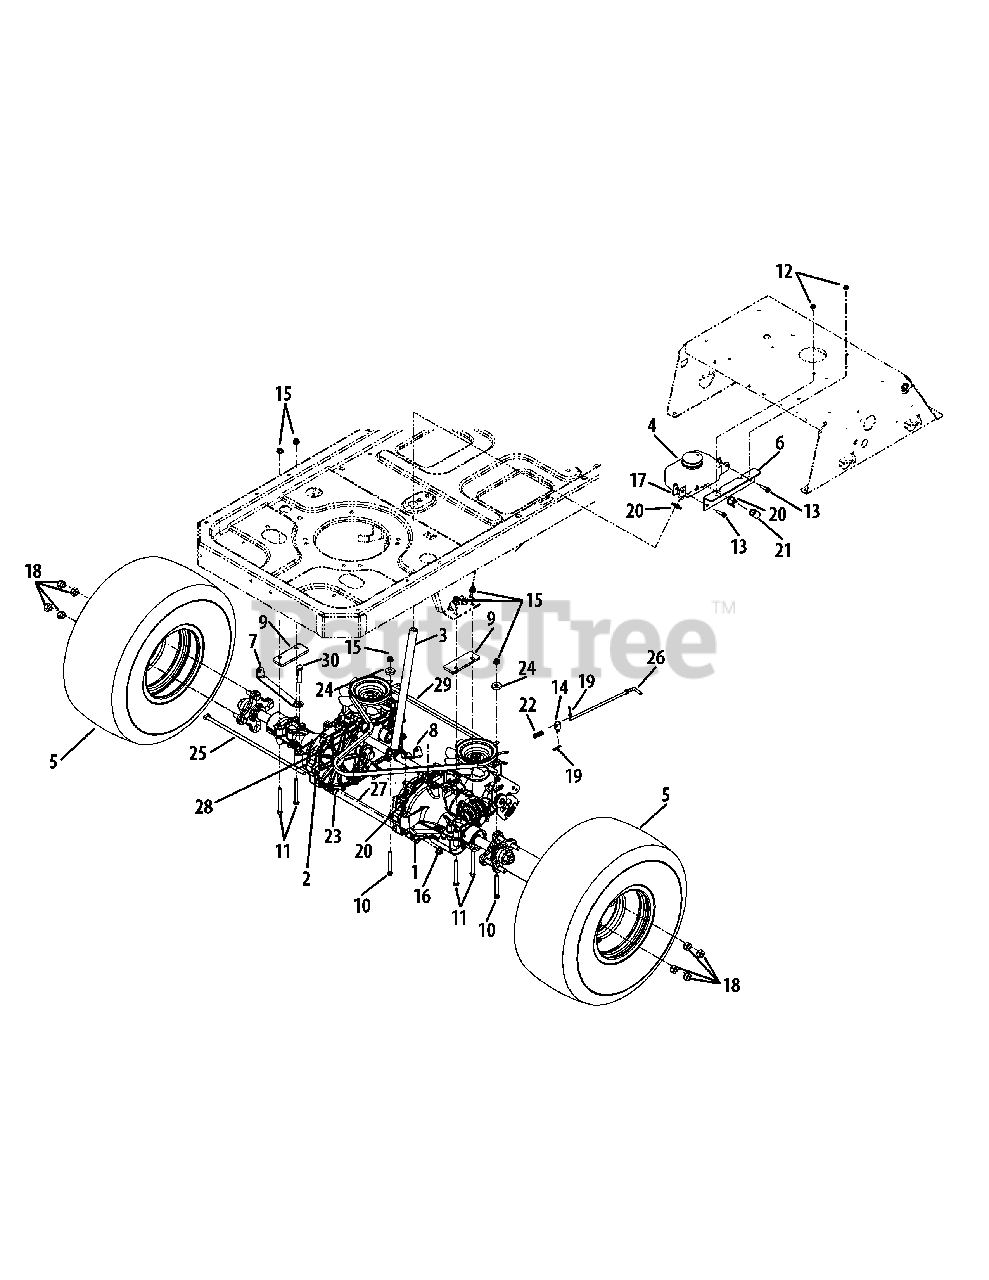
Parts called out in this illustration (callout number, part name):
1	Transmission Ass'y, RH
2	Transmission Ass'y, LH
3	Breather
4	Expansion Tank Ass'y
5	Wheel Assembly Complete 20 x 10 x 8
6	Expansion Tank Bracket
7	Transmission Brace (LH)
8	Transmission Brace (RH)
9	Transmission Spacer
10	Hex Screw 5/16-18 x 2.75
11	Hex Screw 5/16-18 x 3.00
12	Hex Wash S-Tapp Screw 1/4-20 x .50
13	Hex Screw 1/4-20 x 1.0
14	Ferrule, .325 x .312
15	Flange Locknut 5/16-18 Gr. F, Nylon
16	Flange Locknut 3/8-16 Gr. F, Nylon
17	Speed Nut, 1/4-20
18	Lug Nut, 7/16-14
19	Bow Tie Cotter Pin
20	Hose Clamp, 1/2
21	Cap, 1/2 x .870
22	Compression Spring .405 x 1.17
23	Extension Spring .545 x 4.555
24	Flat Washer .35 x 1.0 x .2
25	Rod .337 x 14.75
26	Rod, Bypass
27	Tube 7/16 x 3/4 x 11.3
28	Straight Fitting 9/16 x 1/2
29	V-Type Belt
30	Hex Bolt 5/16-18 x 2.25
